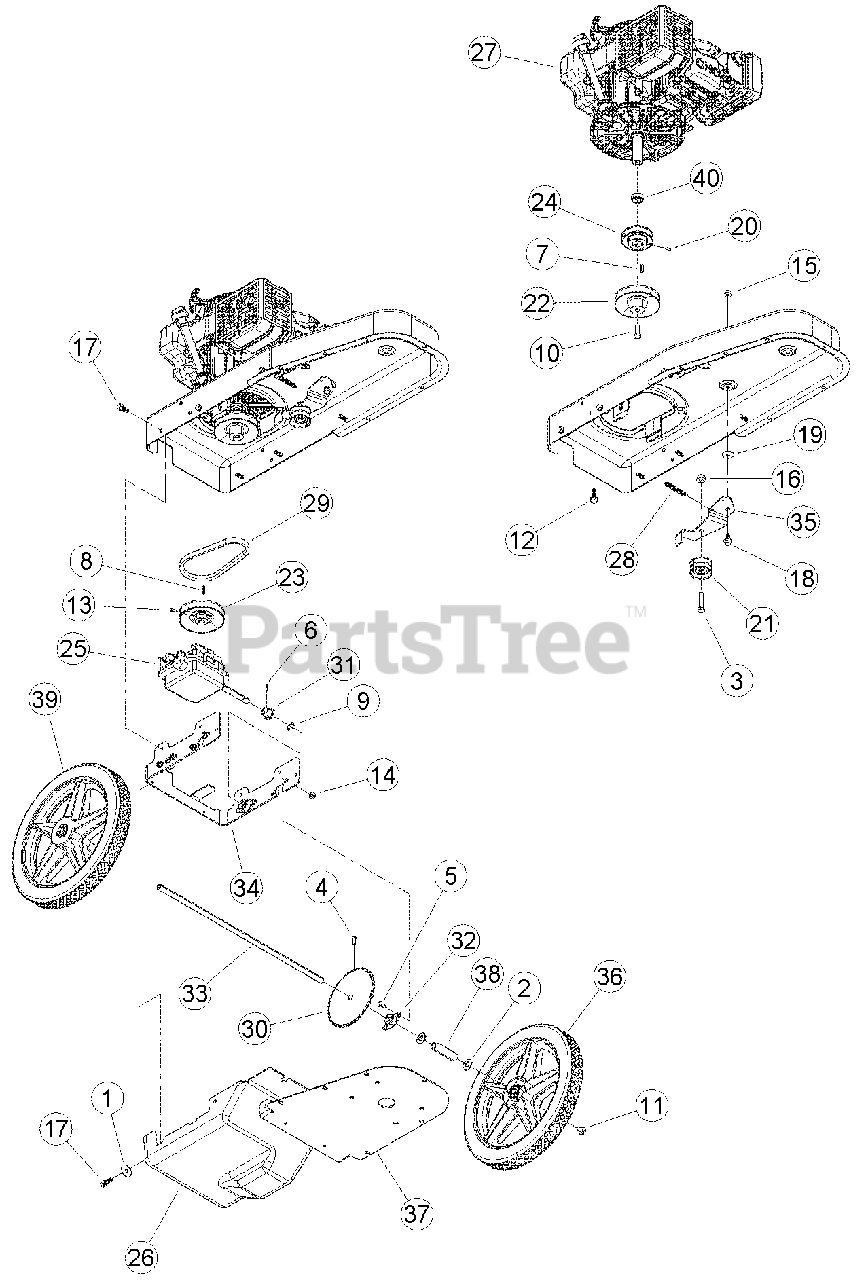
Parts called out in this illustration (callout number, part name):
1	WASHER, 5/16 FENDER
2	WASHER, 1/2 SAE FLAT
3	BOLT, 3/8 X 1-3/4 HEX NC
4	SCREW, 1/4 X 5/8 SQ HD SET
5	BOLT, 1/4 X 5/8 CRG
6	PIN, 1/8 X 3/4 IN. SPRING LOCK
7	KEY, 3/16 SQUARE X 3/4 LONG
8	KEY, 4 MM SQUARE X 20 MM LONG
9	CLIP, 1/2" E
10	BOLT, 3/8 X 1 HEX GR8 NF ZP
11	BOLT, 5/16-18 X 1/2 HEX GR5 SER/FLN
12	SCREW, 3/8-16 X 1 INZP THREAD ROLLING
13	SCREW, 3/16 X 1/2 SQ HD CUP PT SET
14	NUT, 1/4-20 NYLOCK FLANGE
15	NUT, 5/16-18 NYLOCK FLANGE
16	NUT, 3/8-16 NYLOCK FLANGE
17	SCREW, 5/16-18 X 1 INZP THREAD ROLLING
18	BOLT, .150, 5/16-18 X 3/4 ZP FLANGE SHOULDER
19	WASHER, 1.062 OD X .329 ID X .062 FLAT ZP
20	SET SCREW, 10-24 X 3/8 CUP PT SKT
21	IDLER, 1-7/8 DOUBLE FLANGE
22	PULLEY, 4.0 X 7/8 BOREB GROOVE CAPPED
23	PULLEY, 4"X 12 MM AB
24	PULLEY, 2-3/4X 7/8 AB
25	TRANSMISSION, 3-SPEED TRIMMER
26	COVER, UNDERCARRIAGE
27	ENGINE, SUBARU EA190V (FOR SERVICE CONSULT ENGINE OWNER'S MANUAL OR YOUR NEAREST AUTHORIZED SUBARU INDUSTRIAL ENGINE DEALER.)
28	SPRING, IDLER EXTENSION
29	BELT, 4L180 ARIMID
30	SPROCKET, 35B 48T
31	SPROCKET, 35B 9T
32	BEARING, 1/2 INCH FLANGE
33	AXLE, TRIMMER
34	PLATE, TRANSMISSION BASE
35	BRACKET, IDLER ENGAGEMENT
37	PLATE, TRIMMER BASE
38	SPACER, TRIMMER AXLE
40	TUBE, 1-1/16 OD X 0.82 X .455
